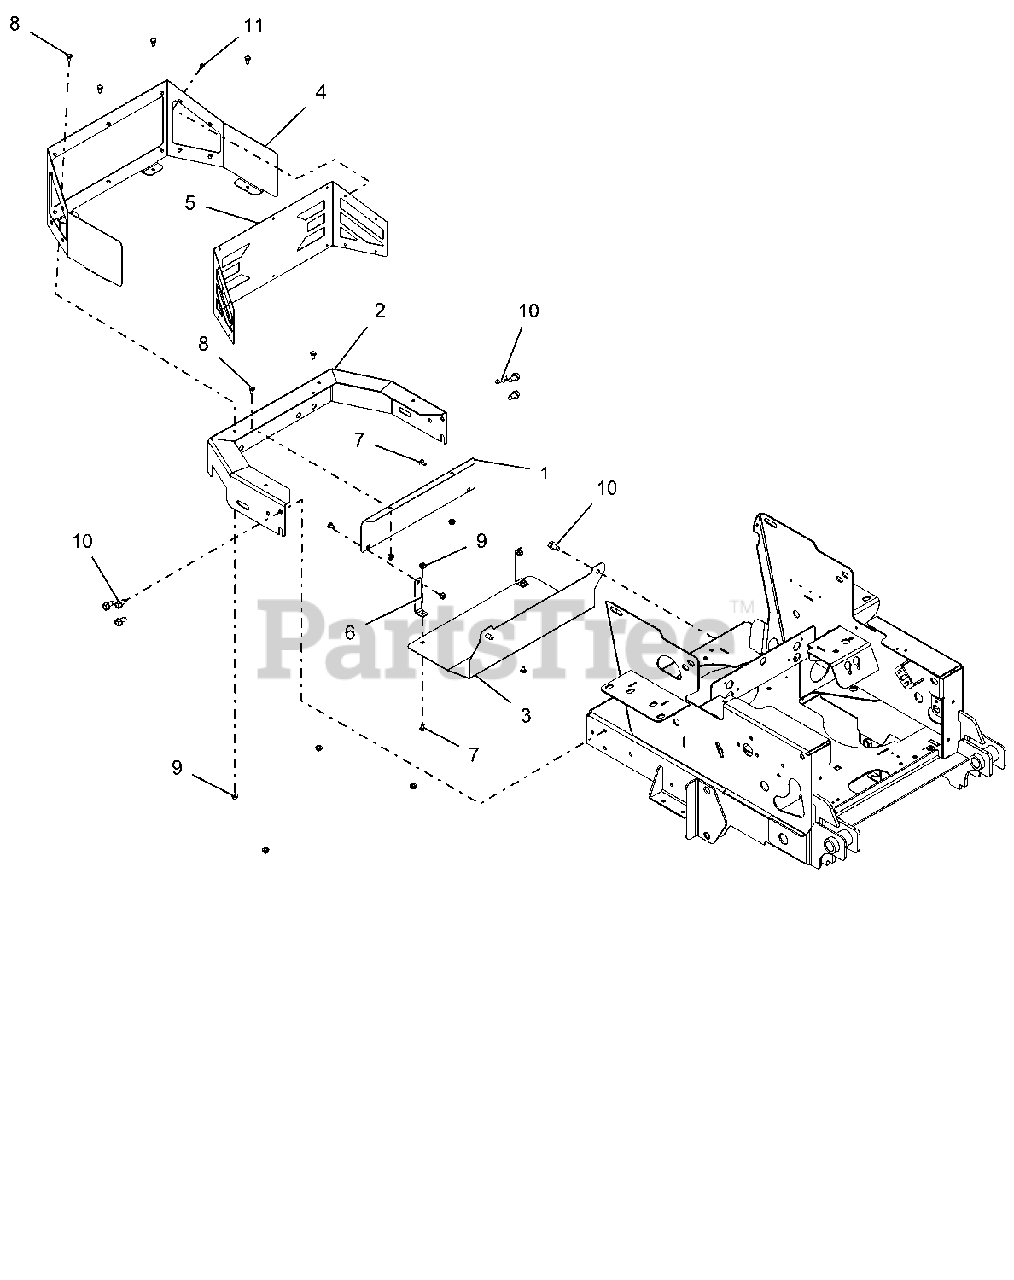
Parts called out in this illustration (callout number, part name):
1	BAFFLE, BUMPER INSERT
2	MAX ZOOM ARIENS BUMPER - BLACK
3	EXHAUST HEAT GUARD - BLACK
4	WLDMT, ENGINE WRAP OUTSIDE
5	ENGINE INNER WRAP-ARIENS-BLK
6	SUPPORT, HEAT SHIELD
7	@BLT-RDHDSQNK .25-20X.50 G5YZ
8	@BLT-HEX .25-20X.50 GR5 YWZC
9	@NUT-LK-TOP-FLG .25-20 YWZC
10	@SCR-TAP .38-16X.75 HWH TR YWZ
11	RIVET, .1875 AL/AL .126-.250
